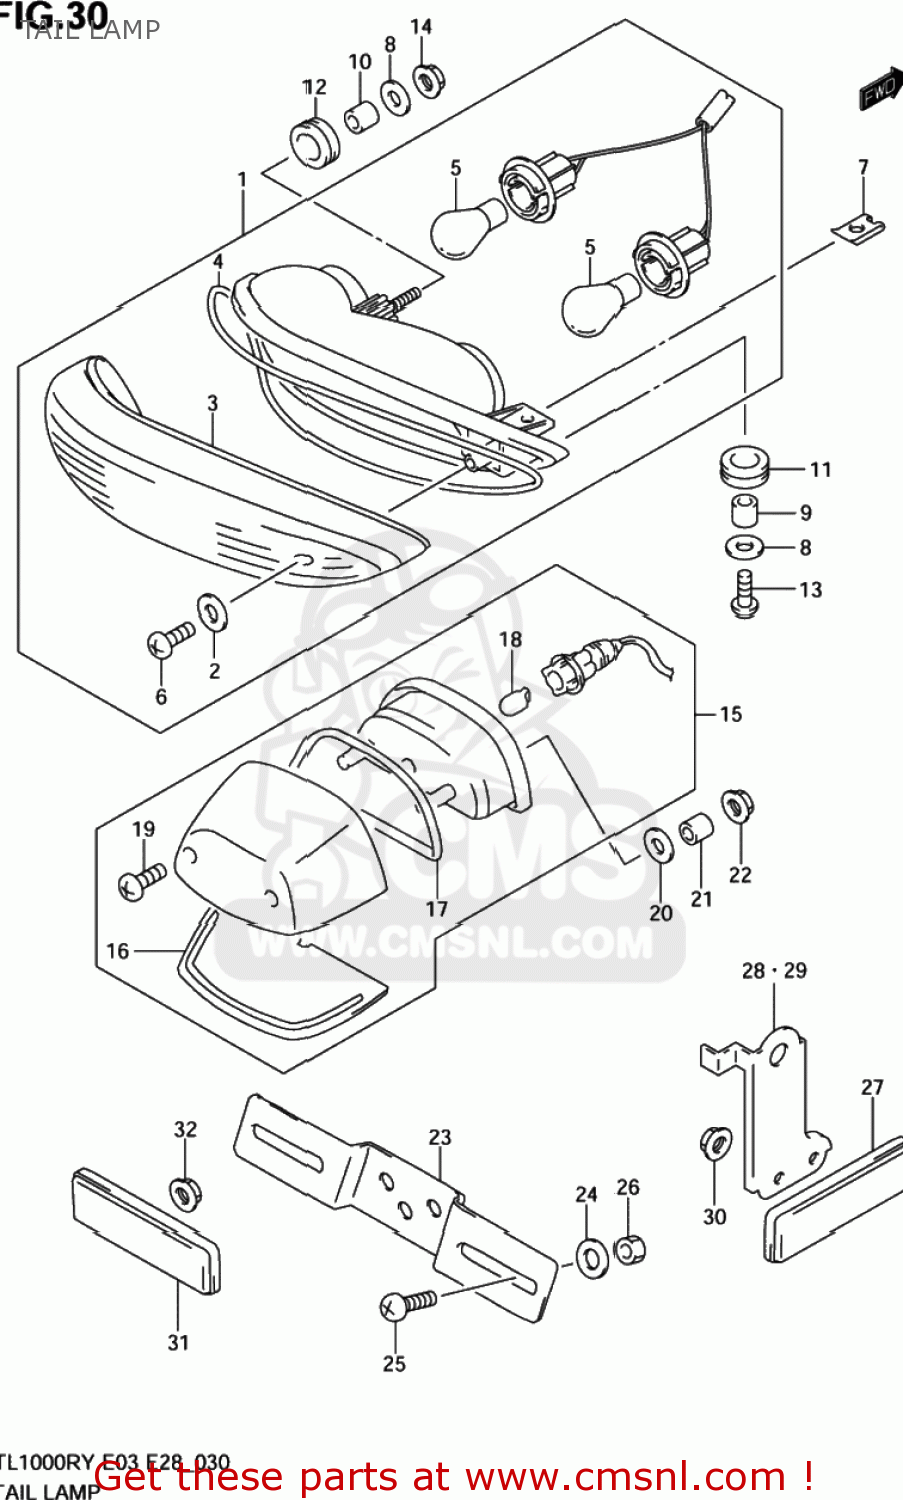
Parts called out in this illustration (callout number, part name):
1	LAMP ASSY,RR COMBINATION
2	GASKET (NAS)
3	LENS
4	GASKET (NAS)
5	BULB(12V21/5W)
6	SCREW
7	NUT
8	WASHER(6.5X20X1.6)
9	SPACER(6.5X10X9)
10	SPACER(6.5X10X12)
11	CUSHION
12	CUSHION
13	SCREW
14	NUT
15	LAMP ASSY,LICENSE
16	LENS
17	GASKET (NAS)
18	BULB(12V5W)
19	SCREW
20	WASHER(6.5X20X1.6)
21	SPACER(5.5X9.5X11.5)
22	NUT
23	BRACKET,LICENSE PLATE
24	WASHER(6.5X20X1.6)
25	SCREW
26	NUT
27	REFLECTOR ASSEMBLY,REAR
28	BRACKET,RR SIDE RR,R
29	BRACKET,RR SIDE RR,L
30	NUT
31	REFLECTOR ASSEMBLY,REAR
32	NUT
